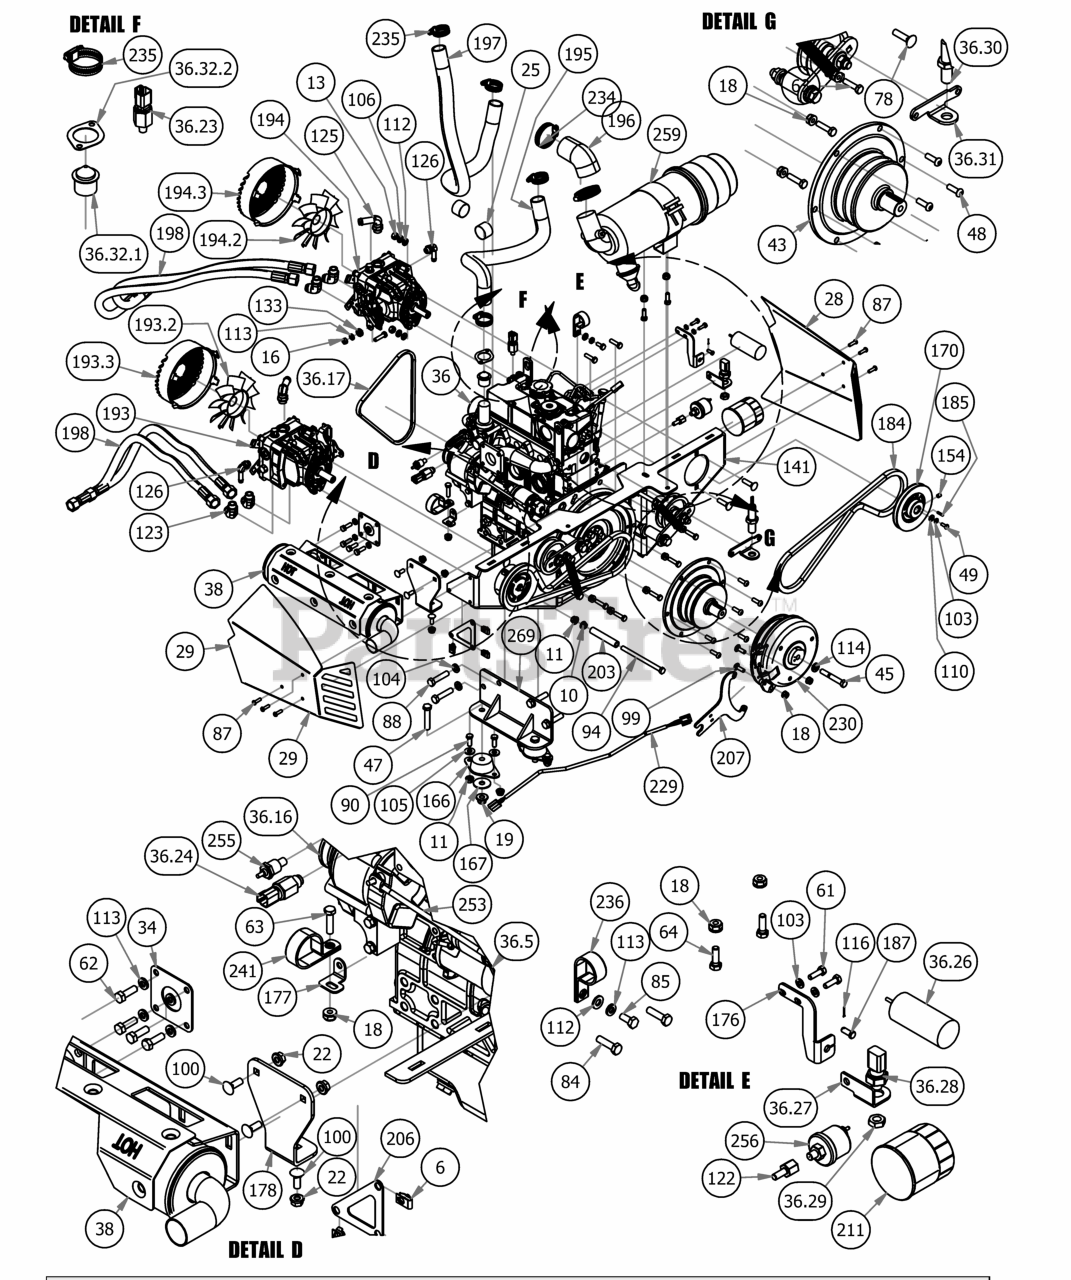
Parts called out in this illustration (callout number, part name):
6	1/4-20 Cage Nut
10	3/8-16 HEX SERRATED FLANGE NUT HARD/ZINC
11	3/8-16 NYLON INSERT FLANGE LOCKNUT (GR.F) ZINC
13	3/8" Hex Nut
18	5/16-18 Nylon Flange Nut
19	1/2-13 NYLON INSERT FLANGE LOCKNUT ZINC
22	5/16" Flange Nut
25	2019 Plastic Mesh Hose Loom
28	2019 Horizontal Pump Cover - Right
29	2019 Horizontal Pump Cover - Left
34	Diesel Muffler Gasket
36	24.7 hp Perkins Engine
36.17	Diesel Engine Belt
36.23	Oil Pressure Sensor
36.24	Coolant Temperature Sensor
36.26	Fuel Shutdown Solenoid
36.27	Barometric Pressure Sensor Bracket
36.28	Barometric Pressure Sensor
36.29	Pressure Sensor Nut for 1100cc Diesel
36.30	Crank Sensor w/ nut
36.31	Crank Sensor Bracket
36.32.1	1100cc Diesel Thermostat
36.32.2	1100cc Diesel Thermostat Gasket
38	2019 Renegade 1100cc Diesel Muffler
43	2019 Diesel Stub Shaft Double V
45	7/16"-20 x 3" Hex Bolt Gr. 8
46	1/2-13 X 90MM HEX FLANGE BOLT W/SHOULDER (GR.8) ZINC
47	1/2" x 3" Hex Bolt
48	5/16-18 x 1 Button Head Torx
49	M6-1.0 X 16MM Hex Bolt
58	3/8-16 X 3-1/2 HEX CAP SCREW (GR.5) ZINC
61	M6x1.0x 20mm 8.8 Hex Bolt
62	M8 x 1.25 x 25mm Hex Head Bolt
63	5/16 x 1 1/4 Hex Bolt
64	5/16" x 1" Bolt
78	3/8 x 1 1/2 Carriage Bolt
84	M8 x 1.25 x 30mm Hex Head Bolt
85	M8x1.20x20MM Hex head bolt
87	Hexagon Socket Button Head Cap Screw
88	12mm Bolt- Diesel
90	3/8" x 1" Hex Bolt
94	3/8-16 x 5 1/2 Hex Bolt
99	5/16" x 1" Carriage Bolt
100	5/16" x 7/8" Carriage Bolt
103	1/4" Lock Washer
104	1/2" Lock Washer
105	3/8" Flat Washer
106	3/8" Lock Washer
108	.635 ID X 1.120 OD X .140 THICK FLAT WASHER NYLON
110	1/4" Flat Washer
112	5/16" Flat Washer
113	5/16" Lock Washer
114	7/16" Lock Washer
116	3/32 X 1/2 Cotter-pin
122	8mm x 1/8 mpt Adaptor
123	2019 Outlaw 90 Degree Pump Fitting #6801-10-08
125	90 Degree Fitting, 1/2 x 3/4, 4601-8-8
126	90 Degree Fitting, 3/8 s 9/16
133	ACS Spacer 3/4x3/8x1/4
141	2020 Diesel Pump Plate Weldment - Painted
154	5/16-24 X 3/8 Set Screw
166	Rubber Compression Mount
167	Snubbing Washer
170	5" Pump Pulley
173	ZT and ACS Handle Spring
174	2019 Outlaw Gen2 Horizontal Push Rod Assembly
174.1	2019 Outlaw Gen2 Horizontal Push Rod
174.2	2019 Outlaw Gen2 Horizontal Push Rod Adjuster
174.3	3/8" Fine Threaded Jam Nut
174.4	Spherical Rod End - Outlaw
174.5	Spherical Rod End - Outlaw
174.6	5/16" LH Fine Threaded Jam Nut
174.7	5/16" RH Fine Threaded Jam Nut
176	Diesel Throttle Bracket 4 Tier
177	Diesel Radiator Hose Clamp Bracket
178	2019 Diesel Muffler Bracket
181	2019 Renegade Belt Tensioner LH
182	2019 Renegade Belt Tensioner LH
184	2019 Renegade Pump Belt
185	5mm x 1.25" Key
187	1/4-5/8 Clevis Pin
193	2019 Rogue/Renegade Left Pump 16cc
193.2	Hydraulic Fan
193.3	Fan Guard 6" Fits wheel Motor Pumps
194	2019 Outlaw Renegade Right Pump 16cc
194.2	Hydraulic Fan
194.3	Fan Guard 6" Fits wheel Motor Pumps
195	2019 Diesel Radiator Hose Upper
196	2019 Diesel Air intake Hose
197	2019 Diesel Radiator Hose Lower
198	2019 Renegade Hydro Hose
203	3/8 hose 4" long
206	Pump Plate Clip Nut Holder
207	2019 Outlaw Renegade Clutch Bracket
211	CAT Oil Filter
229	Clutch Pigtail
230	Clutch for Diesel/Vanguard
234	2-1/2" Hose Clamp
235	1 1/8" Hose Clamp
236	Diesel Hydraulic Hose Clamp
241	Diesel Clamp 1 3/4" Vinyl
253	Red Battery Cable Alternator to Starter Cable
255	Coolant Temperature Sender
256	Oil Pressure Guage with Sender
259	Enginaire Canister VLR-Complet
269	2019 Diesel Motor Mount - Weldment
